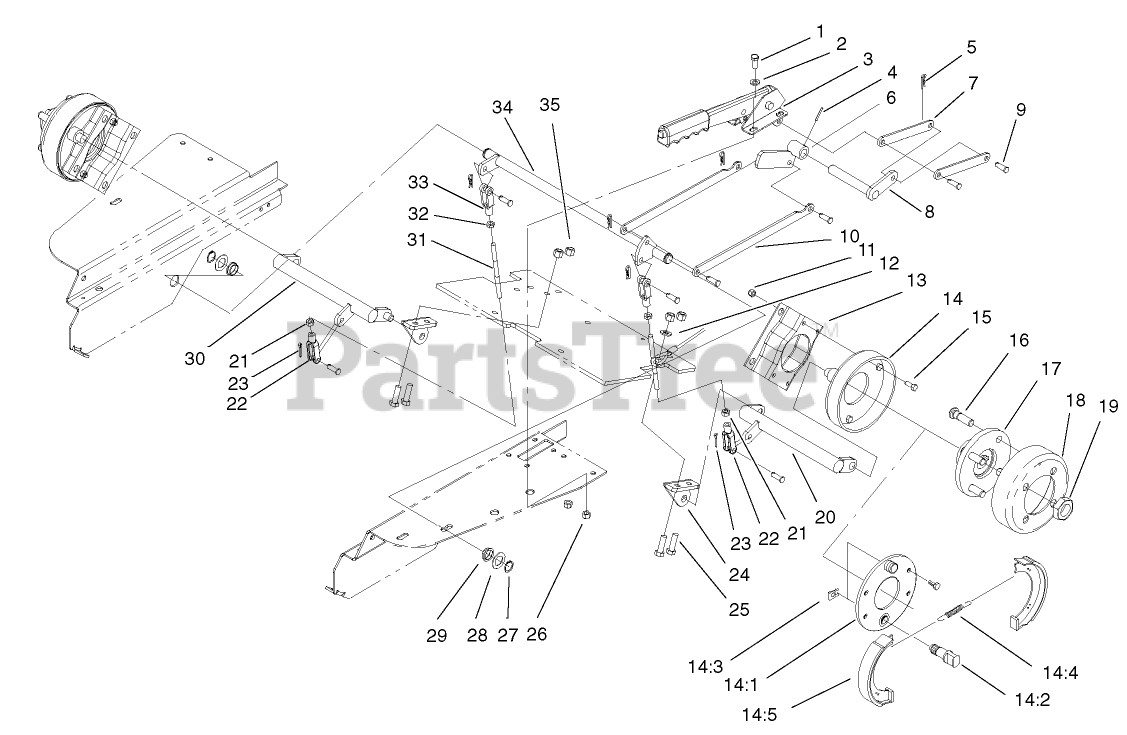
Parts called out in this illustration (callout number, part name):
1	SCREW-HH
2	WASHER-PLAIN
3	LEVER-BRAKE
4	PIN-SPIRAL
5	PIN-COTTER
6	BRAKE HUB ASM
7	LINK-BRAKE
8	TRANSFER SHAFT ASM
9	PIN-CLEVIS
10	LINK - CONNECT
11	NUT-LOCK, NI
12	WASHER-FLAT
13	BRACKET-BRAKE
14	BrakeASM
14:1	PLATE-BACKING
14:2	Cam Shaft
14:3	Clip
14:4	SPRING-RETURN
14:5	SHOE-BRAKE
15	SCREW-HH
16	STUD-DRIVE
17	HUB-WHEEL
18	DRUM-BRAKE
19	NUT-LOCK
20	LH BRAKE LEVER ASM
21	NUT-JAM
22	CLEVIS-ADJUSTABLE
23	PIN-COTTER
24	MOUNT-LEVER, BRAKE, RH
25	SCREW-HH
26	NUT-LOCK, NI
27	Ring-Snap
28	WASHER-FLAT
29	BUSHING
30	RH BRAKE LEVER ASM
31	ROD-BRAKE
32	NUT-JAM
33	YOKE
34	TORSION SHAFT ASM
35	NUT-LOCK, NI
